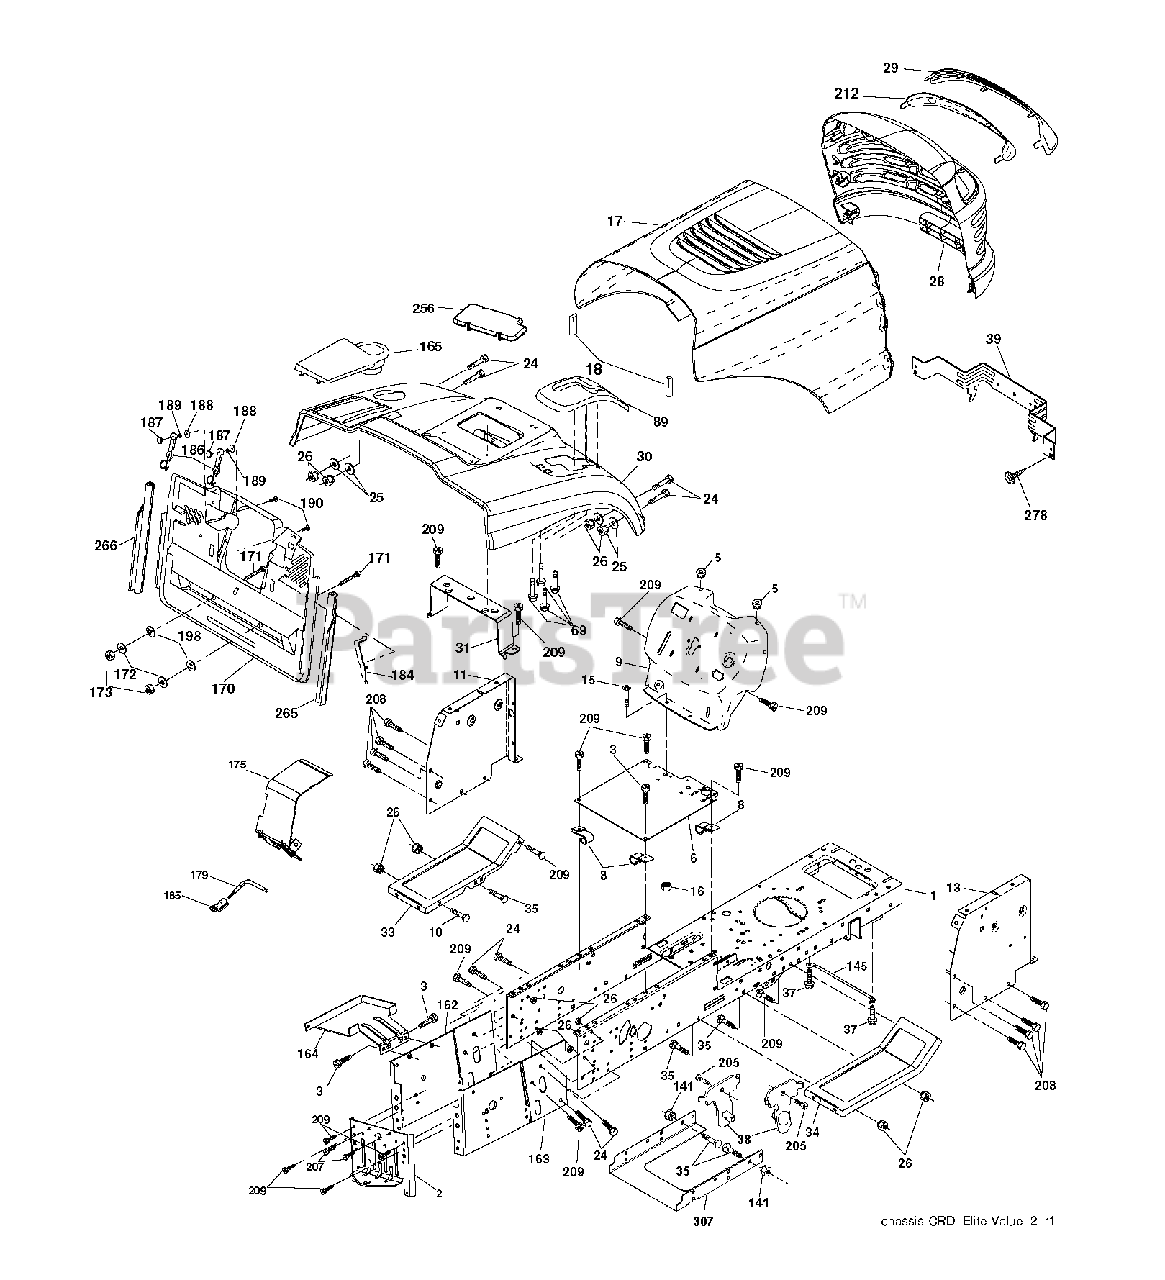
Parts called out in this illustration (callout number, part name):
1	CHASSIS
3	SCREW 3/8-16X3/4
5	BUMPER.RUBBER.HOOD
8	CLIP,INSULATOR
10	BOLT D
11	PANEL.DASH.LH.LTX
13	PANEL DASH RH
16	NUT
18	BUMPER.HOOD.LARGE.1.75"
25	WASHER
26	NUT
31	BRACKET SUPPORT FENDER
39	BRACKET PIVOT
69	SCREW.HI-LO.CONSOLE
141	NUT LOCK FLG 3/8-16 UNC
145	ROD.PIVOT.HOOD
164	SUPPORT
171	BOLT
172	WASHER
186	LATCH ASSY
187	WELDNUT
189	LOCKWASHER
207	SCREW, 5/16-18 X 1/2
208	SCREW 3/8-16X1/2
209	SCREW, 3/8-16X3/4
278	SCREW.#10 X 0.750.BOS THREAD
